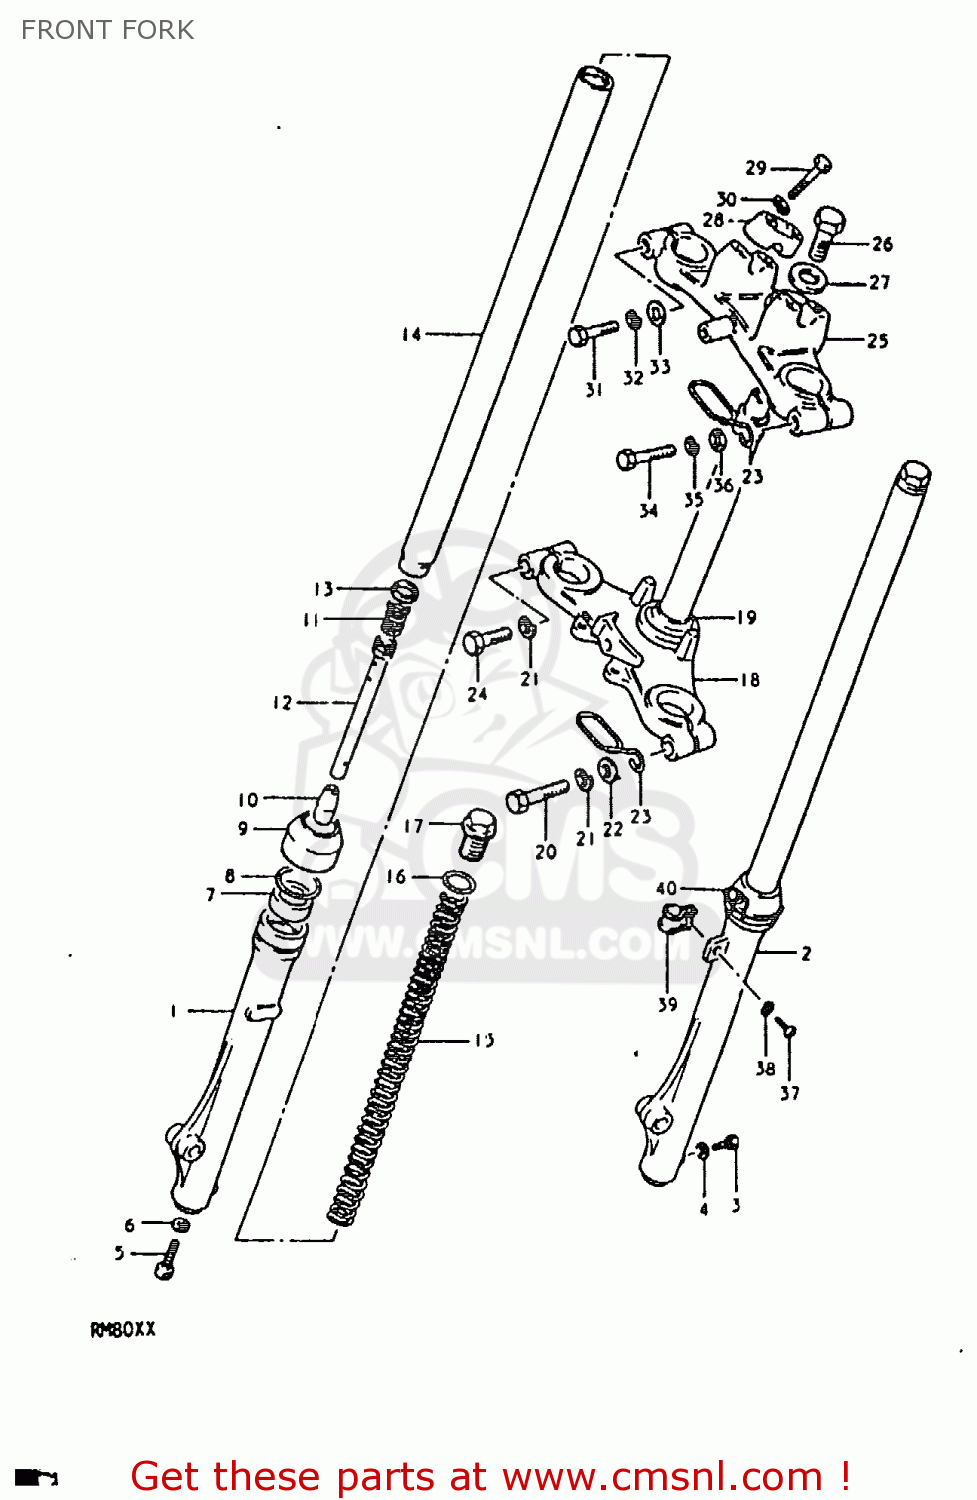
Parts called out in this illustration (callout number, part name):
1	TUBE,OUTER
2	TUBE,OUTER,LEFT
3	BOLT(6X8)
4	GASKET,DRAIN,PLUG (NAS)
5	BOLT(8X27)
6	GASKET (NAS)
7	OIL SEAL,FRONT FORK
8	CIRCLIP,FORK OIL SEAL
9	DUST SEAL,FRONT FORK
10	PIECE,OIL LOCK
11	SPRING,REBOUND
12	CYLINDER,FRONT FORK
13	RING,PISTON
14	TUBE,FORK,INNER
15	SPRING,FRONT FORK
16	O RING
17	BOLT
18	STEM,STEERING
19	RACE,STEERING OUTER LWR
20	BOLT
21	LOCK WASHER
22	WASHER
23	GUIDE,CABLE
24	BOLT,M10X1.25X
25	HEAD,STEERING STEM
26	BOLT,STEERING STEM HEAD
27	WASHER
28	HOLDER,HANDLEBAR
29	BOLT
30	LOCK WASHER
31	BOLT 8X40
32	LOCK WASHER
33	WASHER
34	BOLT 8X45
35	LOCK WASHER
36	WASHER
37	SCREW
38	LOCK WASHER
39	CLIP,FR BRAKE CABLE
40	GUIDE,CABLE
